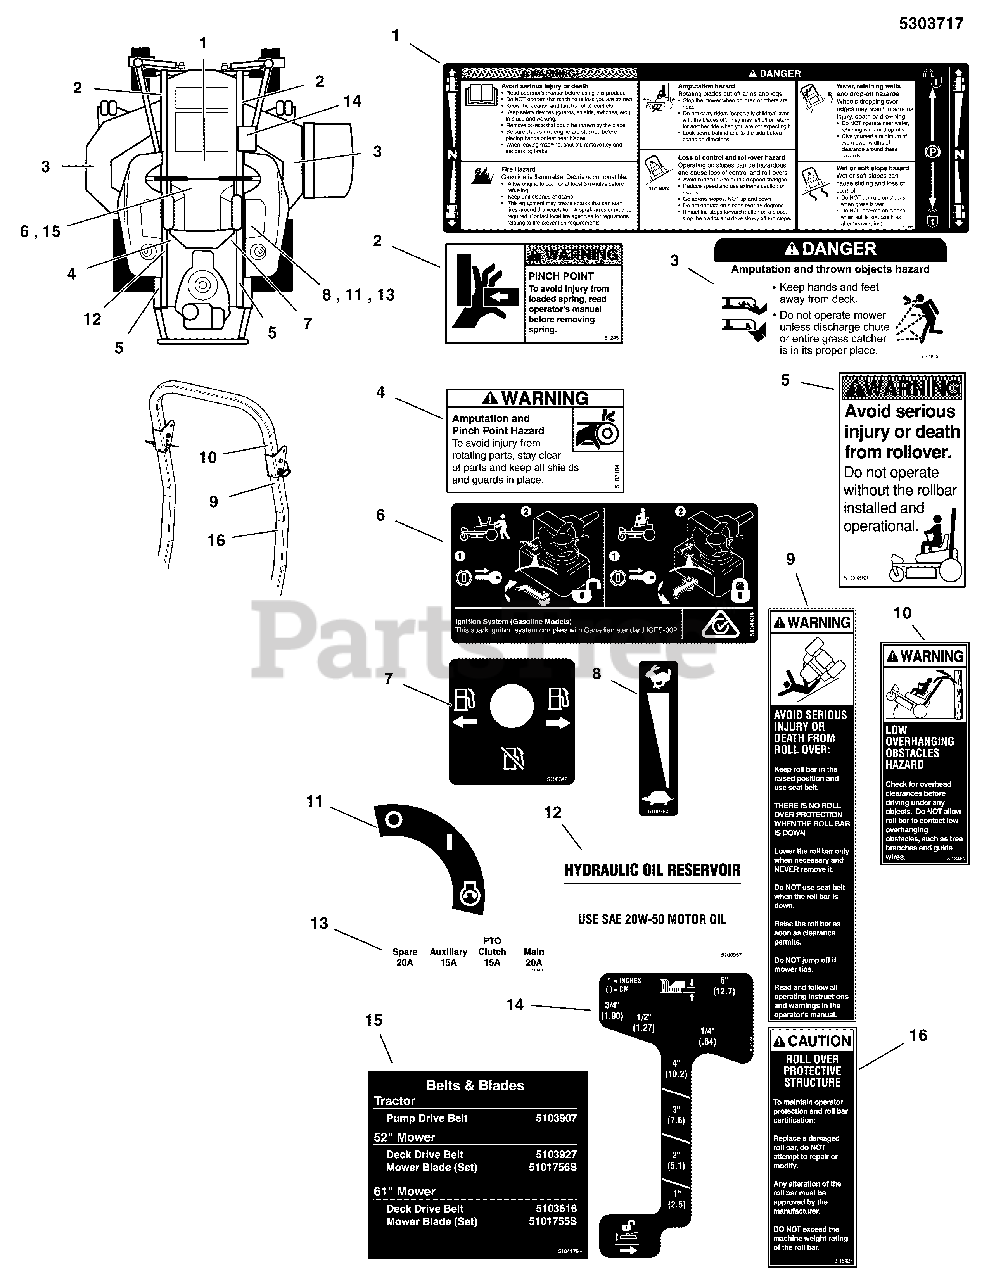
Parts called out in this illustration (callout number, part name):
1	DECAL, MAIN SAFETY
2	DECAL, PINCH POINT
3	DECAL, DANGER DO NOT OPERATE W/O DEFLECT
4	DECAL, WARNING, HAND IN BELT, ENG ONLY
5	DECAL, WARNING, ROLL BAR
6	DECAL, TRANSAXLE RELEASE, ZT4400
7	DECAL, FUEL VALVE
8	DECAL, THROTTLE CONTROL
9	DECAL, WARNING, FOLDING ROPS
10	DECAL, WARNING, OVERHAND, ROPS
11	DECAL, IGNITION SWITCH
12	DECAL, HYDRAULIC OIL, SAE 20W50
13	DECAL, FUSE LOCATION, IS2100
14	DECAL, CUT HEIGHT, IS700/ZTS700
15	DECAL, BELT & BLADE, IS2100Z (V2)
16	DECAL, CAUTION, FOLDING ROPS
